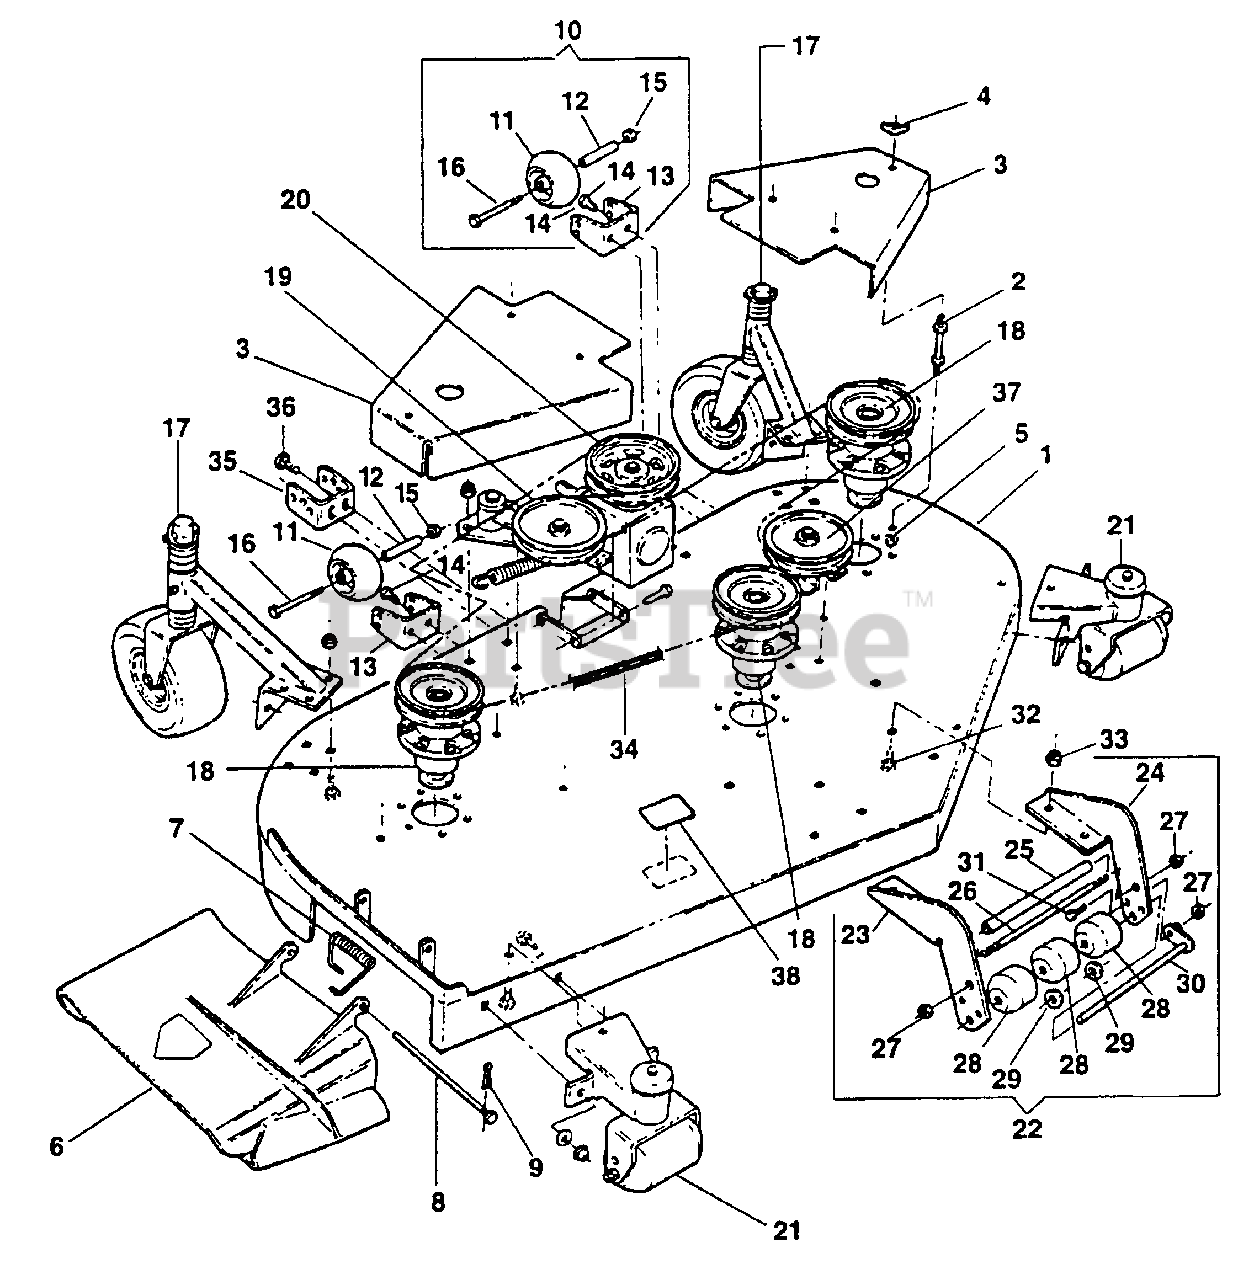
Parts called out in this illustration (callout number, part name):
1	WELDMENT, 73" OFZ MOWER DECK
2	STANDOFF, 3 1/2"
3	GUARD, Belt
4	WINGNUT, 3/8-16
5	NUT, 3/8-16 HEX NYLON LOCK
6	DEFLECTOR, Chute, 73" Deck (Weldment)
7	SPRING, Chute
8	HINGE PIN, Chute
9	PIN, 3/32 x 1" Cotter
10	ASSEMBLY, Gage Wheel
11	WHEEL, Gage
12	SPACER, Gage Wheel
13	FORK, Gage Wheel
14	BOLT, 3/8-16 X 1" GD5 CZ
15	NUT, 1/2-13 Nyloc
16	BOLT, 1/2-13 X 5 GD5 YZ
17	GROUP, 9" Caster (Rear)
18	GROUP, Spindle
19	GROUP, Spring-Loaded Idler
20	GEARBOX, Right Angle
21	ASSEMBLY, Roller
22	ASSEMBLY, Center Deck Roller
23	MOUNT, Roller (R.H.)
24	MOUNT, Roller (L.H.)
25	ROLLER, Tube
26	ROD, Threaded Roller
27	NUT, 1/2-13 Nyloc
28	ROLLER, Low Density Poly
29	WASHER, 5/8" SAE Flat
30	WELDMENT, Pivot Pin
31	BOLT, 1/2-13 X 1-1/2 GD5 CZ
32	BOLT, 3/8-16 x 1" Carriage, Grade 5
33	NUT, 3/8-16 HEX NYLON LOCK
34	BELT, 164" HB Section
35	BRACKET, Rear Deck Hanger
36	BOLT, 3/8-16 x 1" Carriage, Grade 5 (YZ)
37	GROUP, Fixed Idler
38	DECAL, 73 Deck
